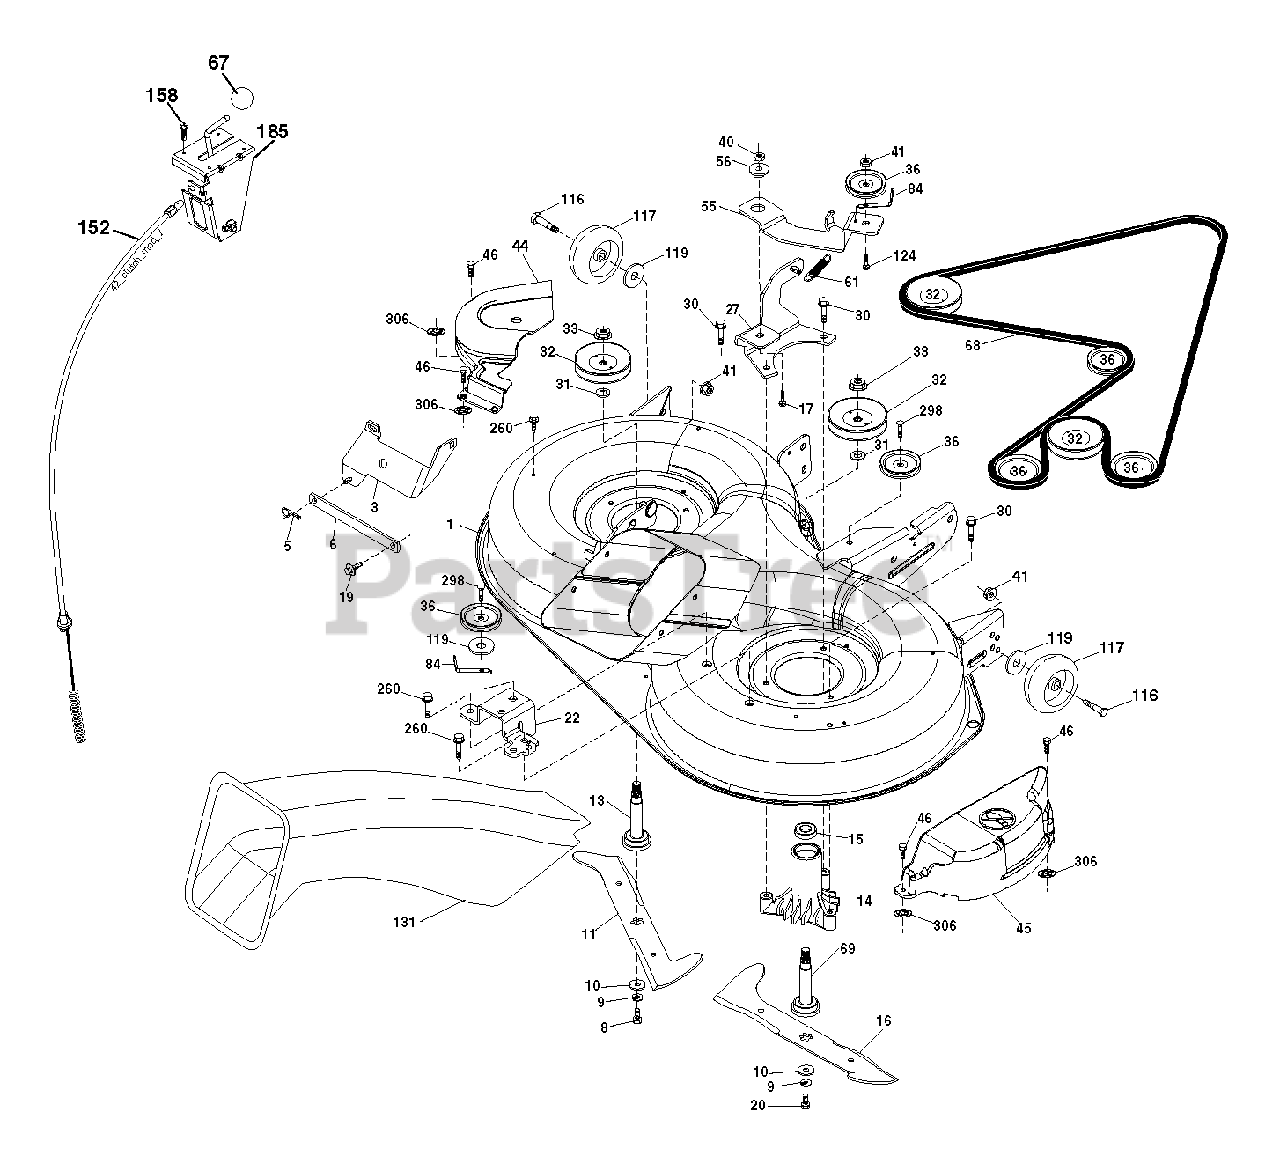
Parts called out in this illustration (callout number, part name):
1	DECK.WLDT.97.CRD.2GWB
3	BRACKET.ASM.BAR.SWAY.CHASS
5	RETAINER-SPRNG RB
6	BAR SWAY
8	Bolt, 3/8-24 X 1.25 Gr8
9	LOCKWASHER
11	BLADE.3N1.LH.CRD.97
13	SHAFT ASM VENT
16	BLADE.3N1.RH.CRD.97
17	BOLT.3/8-14X1.25
19	BOLT SHD 5/16-18
20	BOLT.3/8-24X1.25GR8. LHTHRD
22	BRACKET.SUPT.IDLER.REAR.RH
27	BRACKET.ASM.SUSP.REAR.RH.
30	SCREW, WASHER HEAD
31	WASHER.SPACER.MANDREL
32	PULLEY MANDREL
33	NUT.FLANGE.LOCK.TOP
36	PULLEY.IDLER.4.25
40	LOCKNUT
41	NUT LOCK FLG 3/8-16 UNC
44	OVER.MANDREL.LH.CRD
45	COVER.MANDREL.RH.97.CRD
46	SCREW.1/4-20X5/8
56	SPACER.RETAINER.MOWER
67	KNOB T (3/8 HOLE)
68	BELT.DRIVE.CRD.97.2010
69	SHAFT.ASM.W/LWR.BRG.RH.THREAD
84	KEEPER, BELT IDLER
116	BOLT.SHOULDER.3/8-16X3-5/8
117	WHEEL. GUAGE RALLY
124	BOLT.3/8-16X1.50
158	SCREW
185	HEAD ASM. CABLE CLUTCH
260	SCREW 3/8-16X1/2
298	SCREW LT
